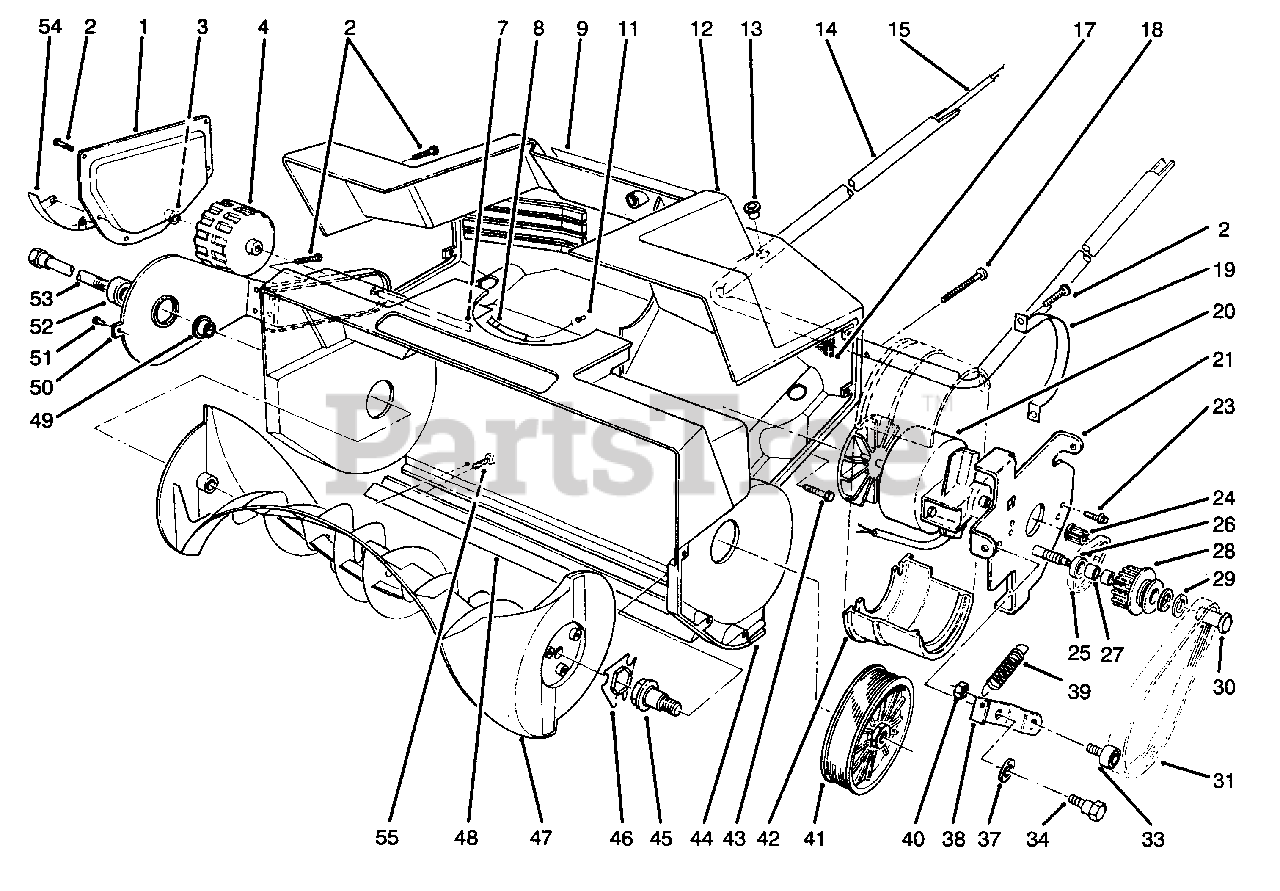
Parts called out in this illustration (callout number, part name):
1	Plate-Side
2	Screw-Pan Hd.
3	Nut-Push
7	Shaft-Axle
8	Relief-Strain
9	Decal-Danger
11	Connector
12	Shroud-Housing
14	Tube-Lower Handle
15	Wire Harness
17	Filter-Foam
18	Screw-Pan Hd.
19	Strap-Motor
21	Motor Plate Assembly
23	Screw-Hex Washer Hd.
24	Pulley-Driver
25	Belt-Timing
27	Bearing-Needle
28	Pulley Assembly-Idler (Incl. Ref. #27)
29	Washer-Thrust
30	Bolt-Idler
31	Belt-Drive
33	Bearing Assembly (Incl. Ref. #40)
34	Screw-Shoulder
38	Bracket-Idler
40	Nut-Lock
41	Pulley-Driven
42	Clamp-Motor Bracket
43	Screw-Hex Hd.
44	Housing-Rotor
45	Shaft-Rotor Driver
46	Coupler-Rotor
50	Bracket-Wheel (Incl. Ref. #52)
51	Rivet-Pop
52	Bearing-Ball
53	Shaft-Rotor
54	Skid-Housing
55	Screw-Pan Hd.
